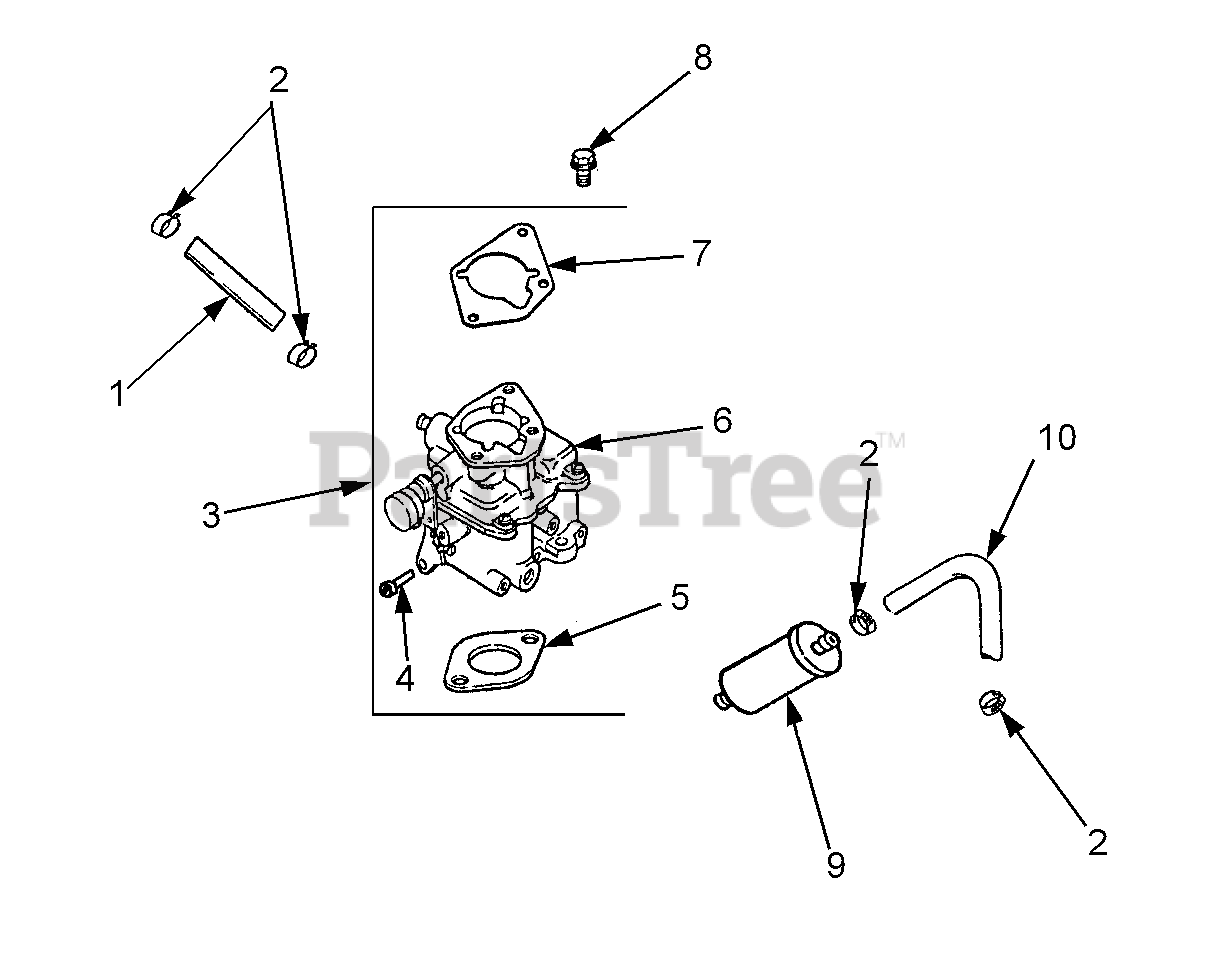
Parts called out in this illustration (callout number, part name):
1	Line, Fuel 10"
2	Clamp, Hose
3	Kit, Carburetor w/Gasket
4	Screw, Throttle Stop
5	Gasket, Carburetor
6	Carburetor Assembly
7	Gasket, Air Cleaner Base
8	Screw, Hex Flange
9	Filter, Fuel
10	Line, Fuel 11"
